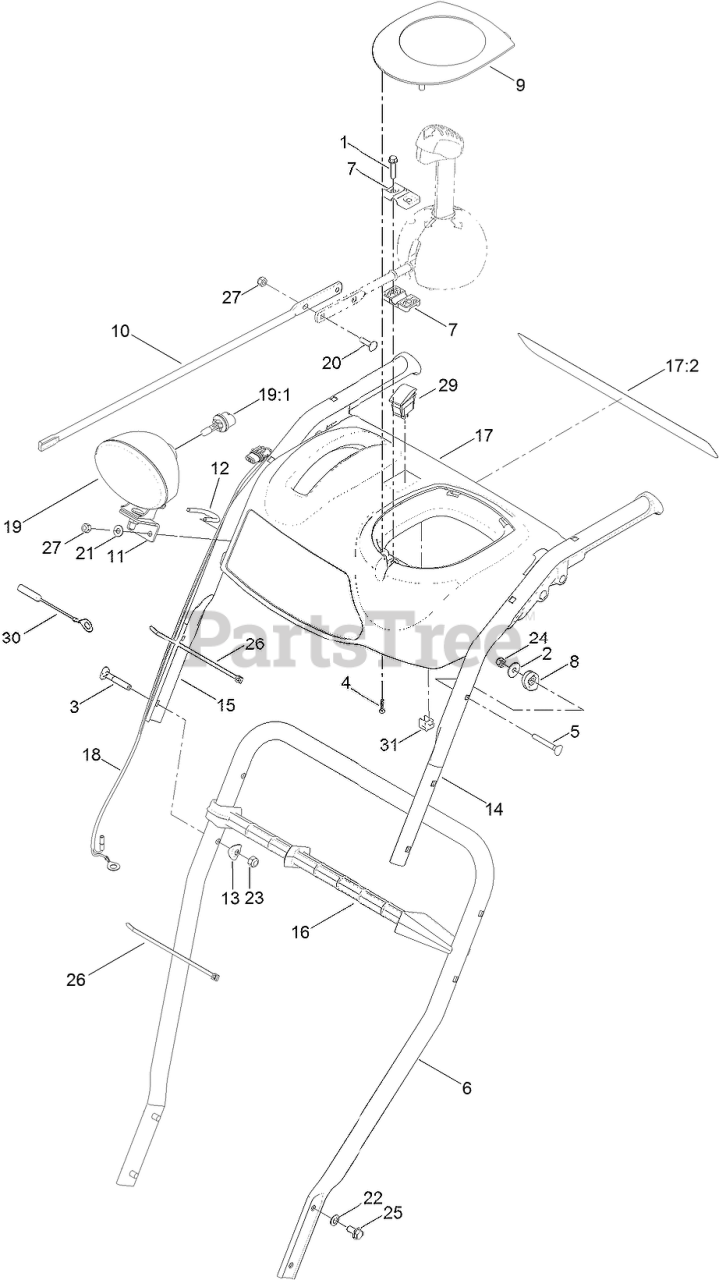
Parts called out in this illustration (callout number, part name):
1	SCREW-PLASTITE
2	WASHER-PLAIN
3	SCREW-HANDLE
4	SCREW-PPH
5	SCREW
6	HANDLE-LOWER
7	SUPPORT-ROD
8	CLAMP-CABLE
9	COVER-PANEL, CONTROL
10	ROD-CHUTE, FRONT
11	BRACKET-LIGHT
12	CLAMP
13	WASHER
14	HANDLE-UPPER, LH
15	HANDLE-UPPER, RH
16	STICK-CLEANOUT
17	CONTROL PANEL ASM
17:2	DECAL-CONTROL
18	HARNESS-WIRE, HEATED GRIPS
19	HEADLAMP ASM
19:1	LAMP-12 VOLT
20	SCREW-CARR
21	WASHER-FLAT
22	WASHER-BELLEVILLE
23	NUT-LOCK, NI
24	NUT-LOCK, NI
25	SCREW-HWHTF
26	TIE-CABLE
27	NUT-LOCK, NI
29	SWITCH-ROCKER, OFF-NONE-ON
30	HARNESS-WIRE, GROUND JUMPER
31	CLIP-EDGE
